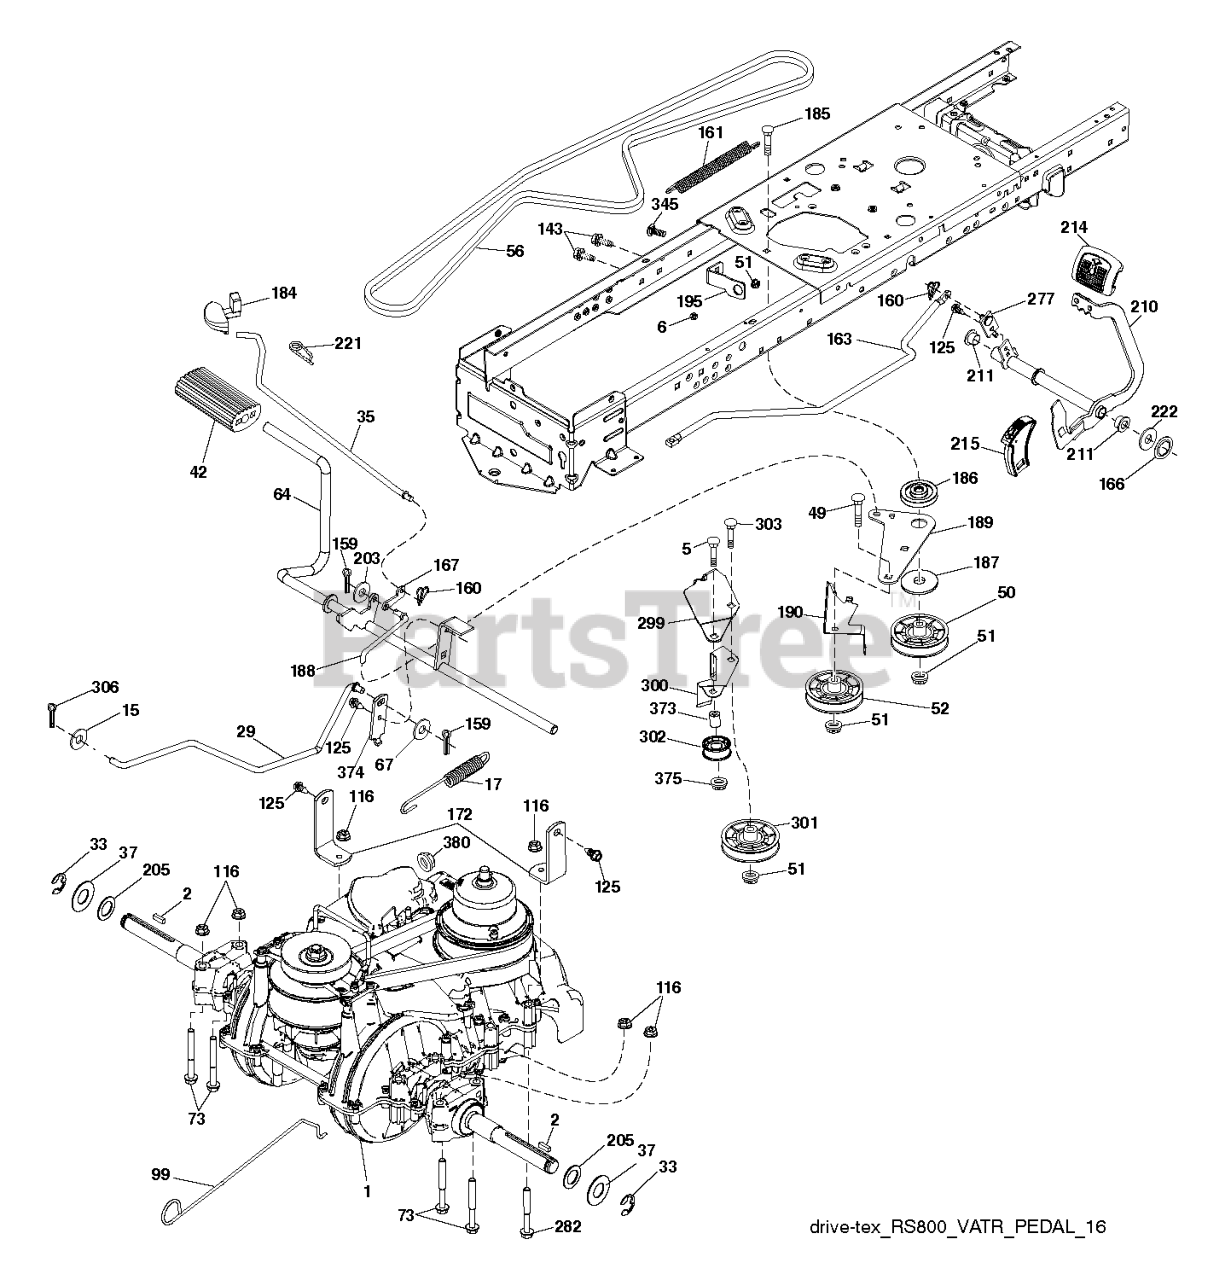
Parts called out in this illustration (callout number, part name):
2	Key, Square 2.5 x .1845/.1865 (AYP part number)
5	Bolt, Hex 3/8-16 UNC x 2-1/4 (AYP part number)
6	Bushing Snap Nyl Blk Fuel Line
15	Washer 13/32 x 1-3/16 x 12 Gauge (AYP part number)
17	SPRING.BRAKE.VARIATOR
29	BRAKE.VARIATOR.SD3
33	E-ring #5133-75 (AYP part number)
35	ROD ROD.PARKINGBRAKE.GT.HUSQ/P
37	WASHER.HARDENED
42	Cover Pedal Blk Round (AYP part number)
49	Bolt, Carriage 3/8-16 x 1-3/4 Grade 5 (AYP part number)
50	IDLER.FLAT.910.OFFSET
51	NUT LOCK FLG 3/8-16 UNC
52	IDLER.V-GROOVE.910.OFFSET
56	BELT.DRIVE.MOWER.TEX.42"
64	SHAFT VARIATOR PEDAL CROSS
67	WASHER.NYLON;13/32X13/16X.109
73	BOLT HEX 5/16-18 GR 5
99	ROD.BYPASS.VARIATOR.GEN2
116	NUT LOCK HEX FLANGE 5/16-18
125	SCREW
143	SCR 5/16-18 X 1/2 SELFTAP ZN
159	Pin Cotter 1/8 x 3/4 CAD. (AYP part number)
160	RETAINER CLIP
161	X Spring Return Clutch 6 75 (AYP part number)
163	ROD.CONTROL.PEDAL.VARIATOR
166	NUT.PUSH.625
167	LATCH.BRAKE.SPRING
172	STRAP.TORQUE.VARIATOR
184	HANDLE.PARKING.BRAKE.H (BLK)
185	Bolt, Carriage 3/8 - 16 x 2-3/4 (AYP part number)
186	SPACER.RETAINER
187	Washer 12/32 x 2 x 10 Gauge (AYP part number)
188	LINK.CLUTCH.GROUND DRIVE.LONG
189	BELLCRANK.GROUND.DRIVE.TEX.
190	KEEPER.BELLCRANK.DRIVE
195	BRACKET.BRAKE.BRAKE.VAR.SD
203	Washer, Nut Lock Hex w/Ins. 5/6-18 (AYP part number)
205	Washer 25/32 x 1-5/8 x 16 Gauge (AYP part number)
210	PEDAL.ASM.ROCKET.VARIATOR.LT
211	Bearing Nylon Blk 629 Id (AYP part number)
214	PEDAL.FORWARD.PAD.TEX
215	CAP.PEDAL.REVERSE.VARIATOR
221	RETAINER.SPRING.CLIP.H
222	WASHER 21/32 X 1-1/4 X 10 GA.
277	SUBASM.LINK.ROCKER.PEDAL
282	BOLT HEX FLGHD 5/16-18X3 GR. 5
299	BRACKET.MOUNT.IDLERS
300	KEEPER.IDLERS.REAR.VARIATOR
301	PULLEY.IDLER.V-GROOVE
302	PULLEY.IDLER.FLAT.2"
303	Bolt, Carriage 3/8-16 x 2 1/4 (AYP part number)
306	Pin Cotter 1/8 X 1 Cad (AYP part number)
345	Bolt Rdhd Sht Sqnk 3/8 - 16 x 3/4 (AYP part number)
373	SPACER.IDLER
374	ARM.CONTROL.BRAKE
375	Nut, Hex, Lock Hex w/wsh 3/8-16
380	NUT.FLG.NYLOCK.1/4-20.GR.G.ZY
